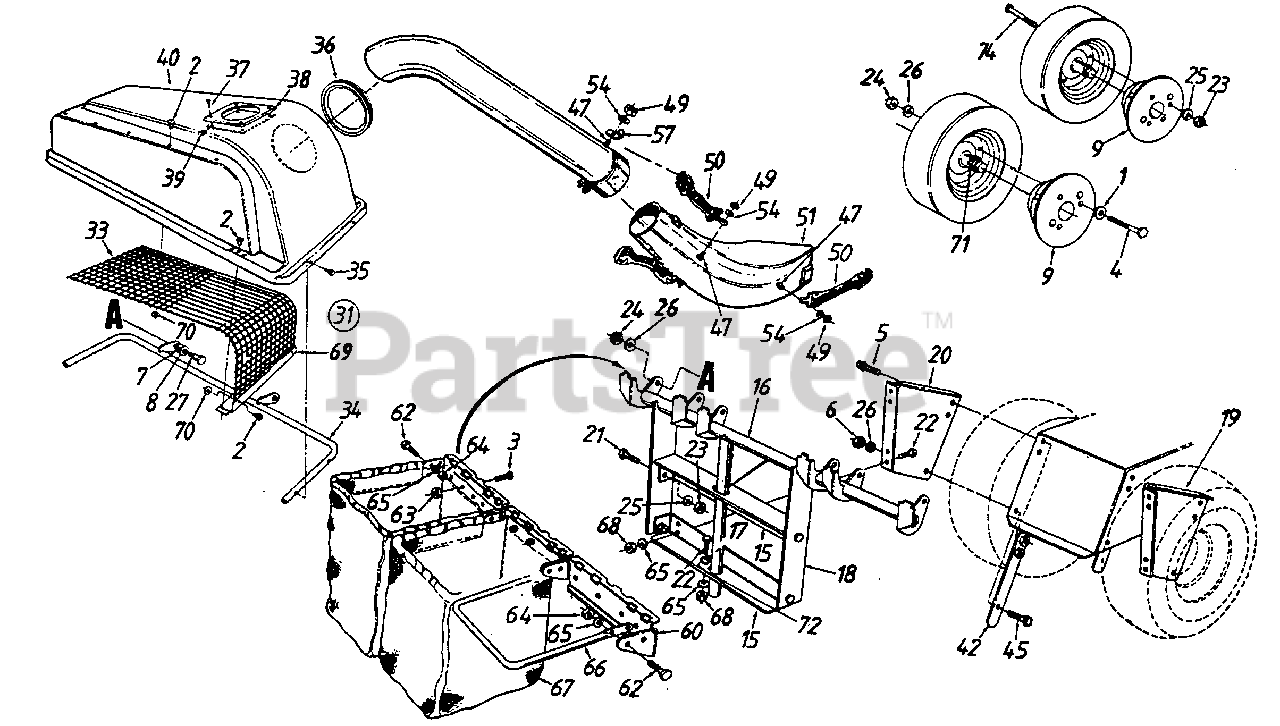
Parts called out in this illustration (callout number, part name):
1	Fl-Wash. .385" I.D.
2	Pop Rivet
3	Truss Mach. Scr. #10-24 x .38"
4	Hex Bolt 3/8-16 x 4.5" Lg.
5	Hex Wash. Hd. Tap Scr. 5/16-1 8 x .62"
6	Hex Nut 3/8-24 Thd.
7	Bell-Wash. .515" I.D.
8	Fl-Wash. .510" I.D.
18	Catcher Latch and Support Brkt.
22	Hex Bolt 1/4-20 x .62" Lg.-Grade 5
23	Hex Nut 5/16-18 Thd.
24	Hex Nut 3/8-16 Thd.
25	L-Wash. 5/16" I.D.
26	L-Wash. 3/8" I.D.
27	Shld. Bolt 3/8-16 x .500" Dia.
31	Grass Catcher Cover Ass'y. Comp.
33	Screen
36	Tube Seal
37	Truss Mach. B-Tap Scr. #10 x .5" Lg.
38	Plastic Plate
39	Speed Nut
40	Grass Catcher Cover
47	Hex Bolt 1/4-20 x .50" Lg.
49	Hex Ins. L-Nut 1/4-20 Thd.
50	Retainer Strap Ass'y.
51	Discharge Chute
54	L-Wash. .270" I.D. x .57" O.D.
57	Retainer Hook Brkt.
62	Hex Bolt 1/4-28 x .75" Lg.
63	Hex Sems Nut #10-24 Thd.
64	Hex Nut 1/4-28 Thd.
65	L-Wash. 1/4" I.D.
66	Catcher Bag Frame
67	Grass Catcher Bag
68	Hex Nut 1/4-20 Thd.
71	Foam Strip 1-1/8" x 1-1/2" x 3/8"
74	Hex Bolt 5/16-18 x 4" Lg.
